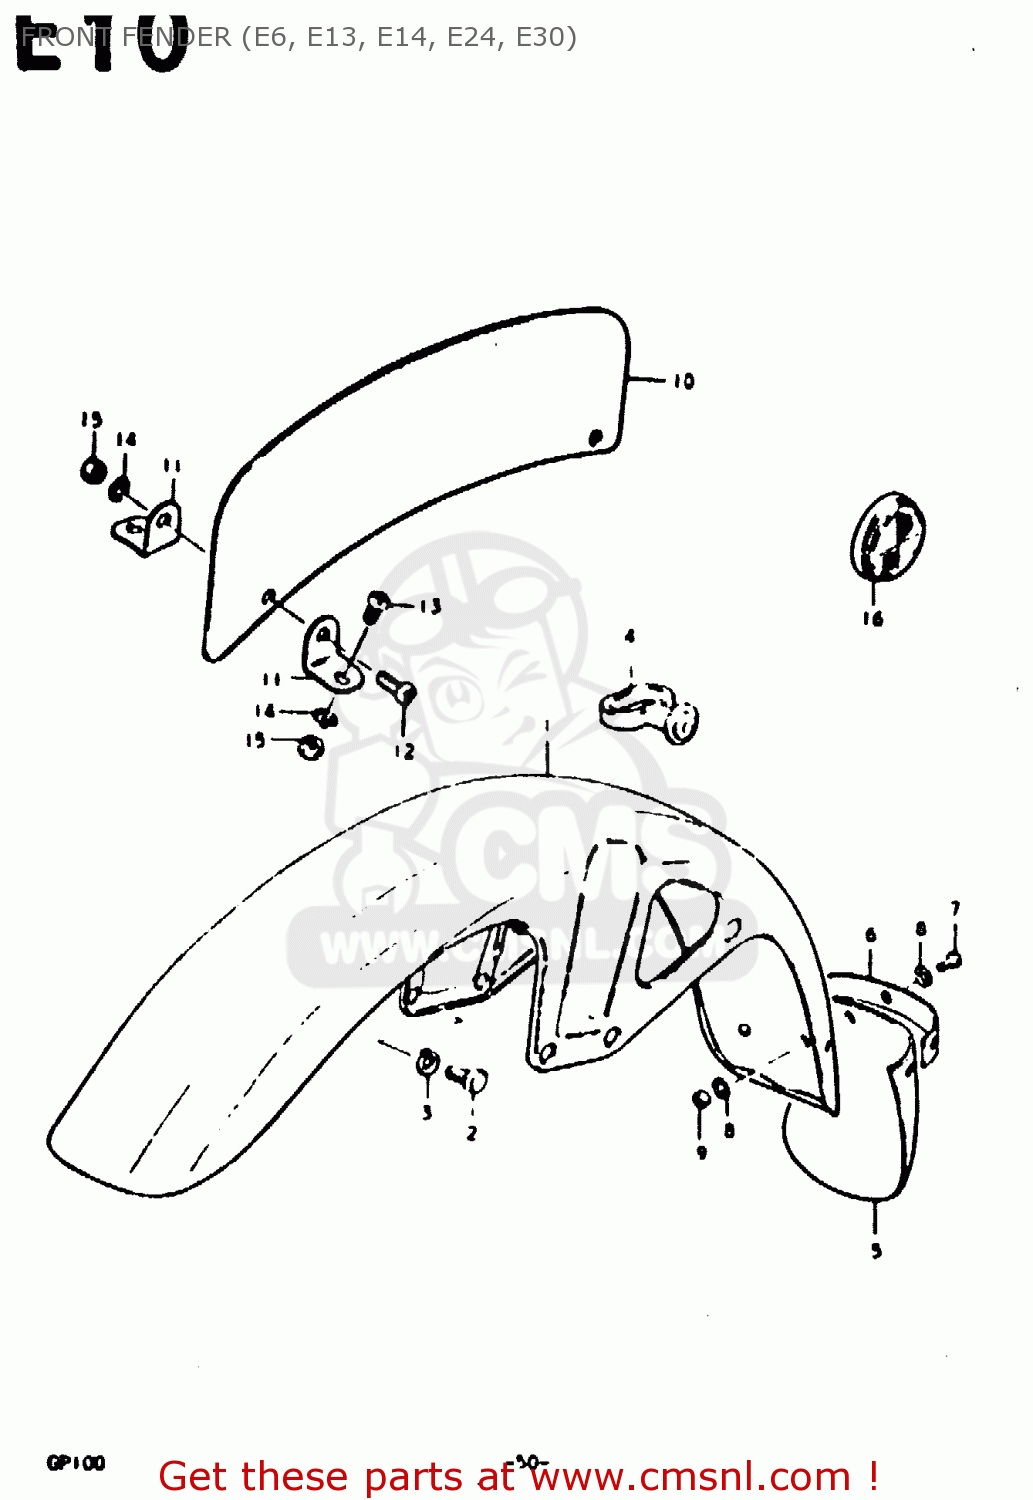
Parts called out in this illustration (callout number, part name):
1	FENDER, FRONT
2	BOLT
3	LOCK WASHER
4	GUIDE,CABLE
5	FLAP,MUD
6	PLATE,MUDFLAP
7	SCREW 4X10
8	WASHER
9	NUT 4MM
10	PLATE, FRONT LICENCE
11	PLATE, LICENCE FITTING
12	SCREW
13	SCREW
14	LOCK WASHER
15	NUT
16	REFLEX REFLECTOR,FR
